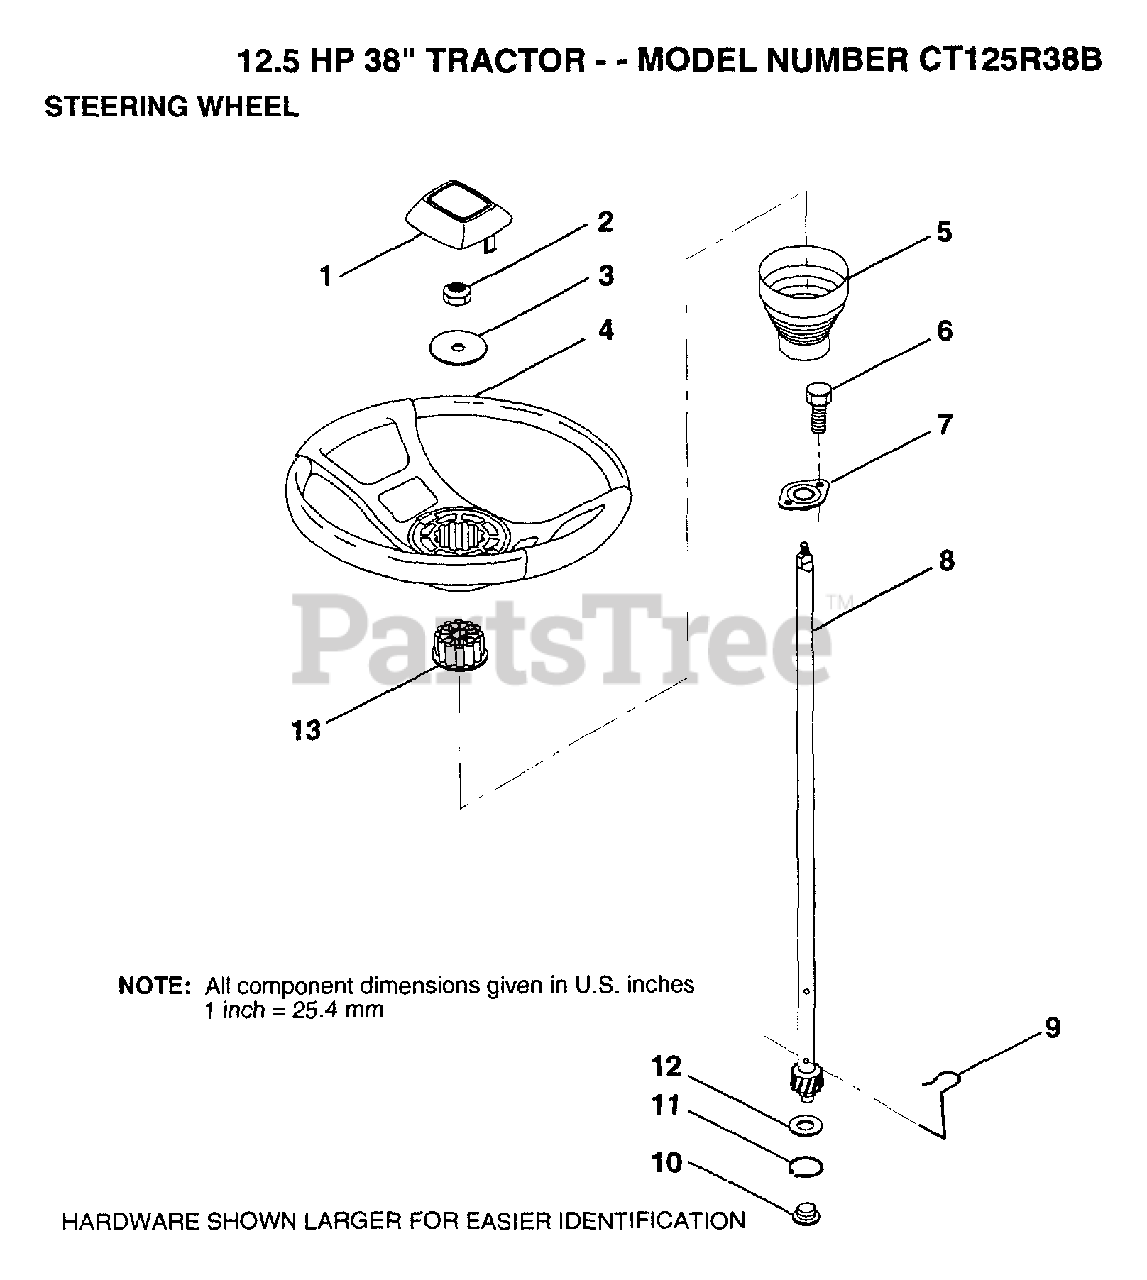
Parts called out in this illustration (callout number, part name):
1	ST WHL INSERT CAP
2	GRIPCO NUT
3	WASHER T
5	SLEEVE STEERING
9	STEERING CLIP
10	BUSHING STEER LWR
11	RING
12	WASHER LT
13	ADAPTER-WHEEL LT
